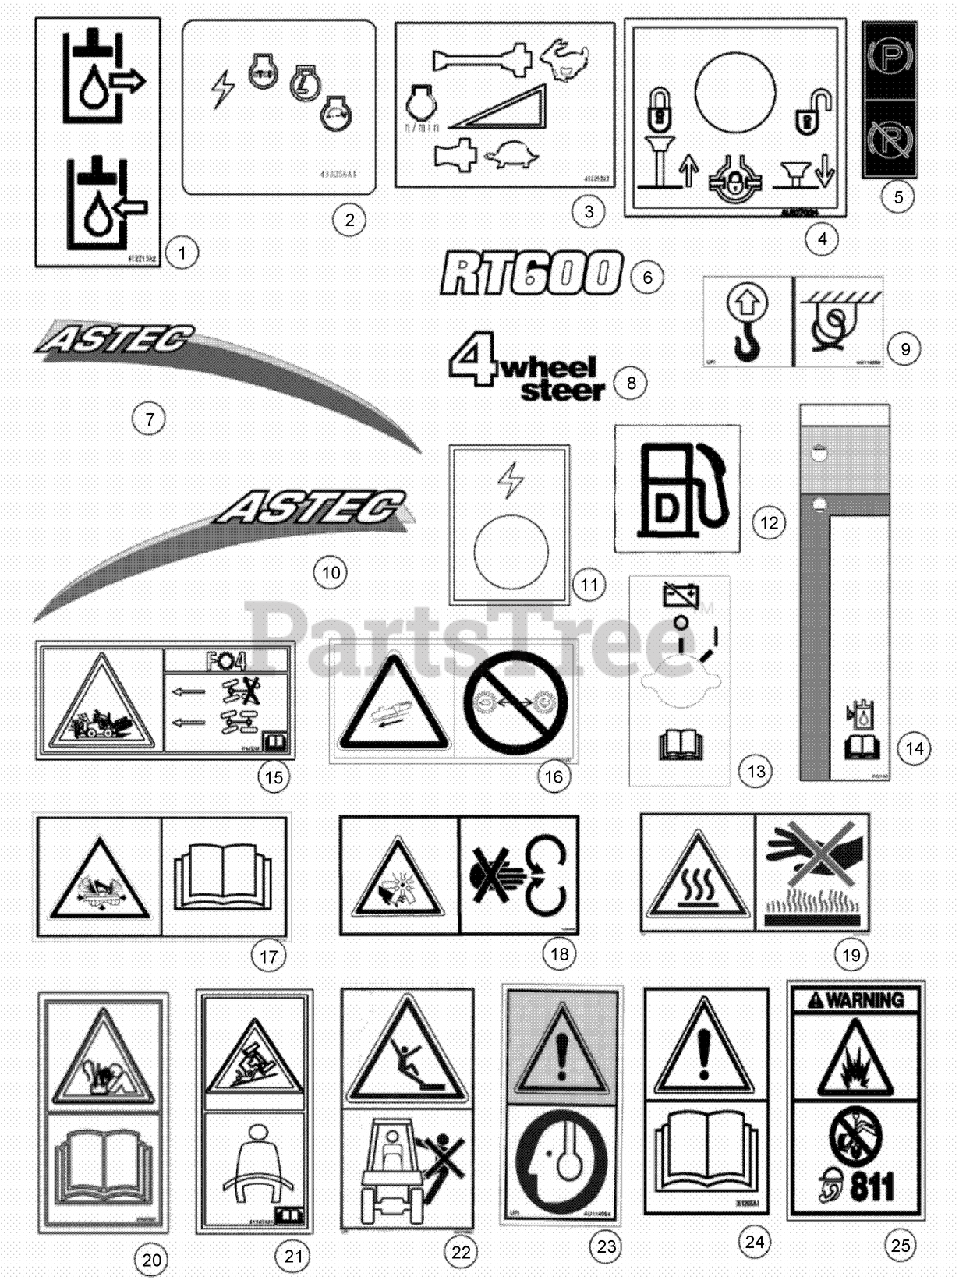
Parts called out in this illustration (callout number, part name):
1	DECAL-Hydraulic Oil, Supply / Return
2	DECAL-Key Switch
3	DECAL-Throttle
4	DECAL-Instrument Panel, RH
5	DECAL-Parking Brake
6	DECAL-RT600
7	DECAL-Astec
8	DECAL-4 Wheel Steering
9	DECAL-Tie Down / Lift Hook
10	DECAL-Astec
11	DECAL-Instrument Panel, RH
12	DECAL-Diesel Fuel
13	DECAL-Master Disconnect Switch
14	DECAL-Hydraulic Oil Level
15	DECAL-Front Steering
16	DECAL-Unexpected Movement
17	DECAL-Fluid Pressure
18	DECAL-Fan Entanglement
19	DECAL-Hot Surface
20	DECAL-Battery Explosion
21	DECAL-Warning, Fasten Seat Belt
22	DECAL-No Riders
23	DECAL-Warning, Hearing Protection Required
24	DECAL-Read Operators Manual
25	DECAL-Warning, Call Before Digging
